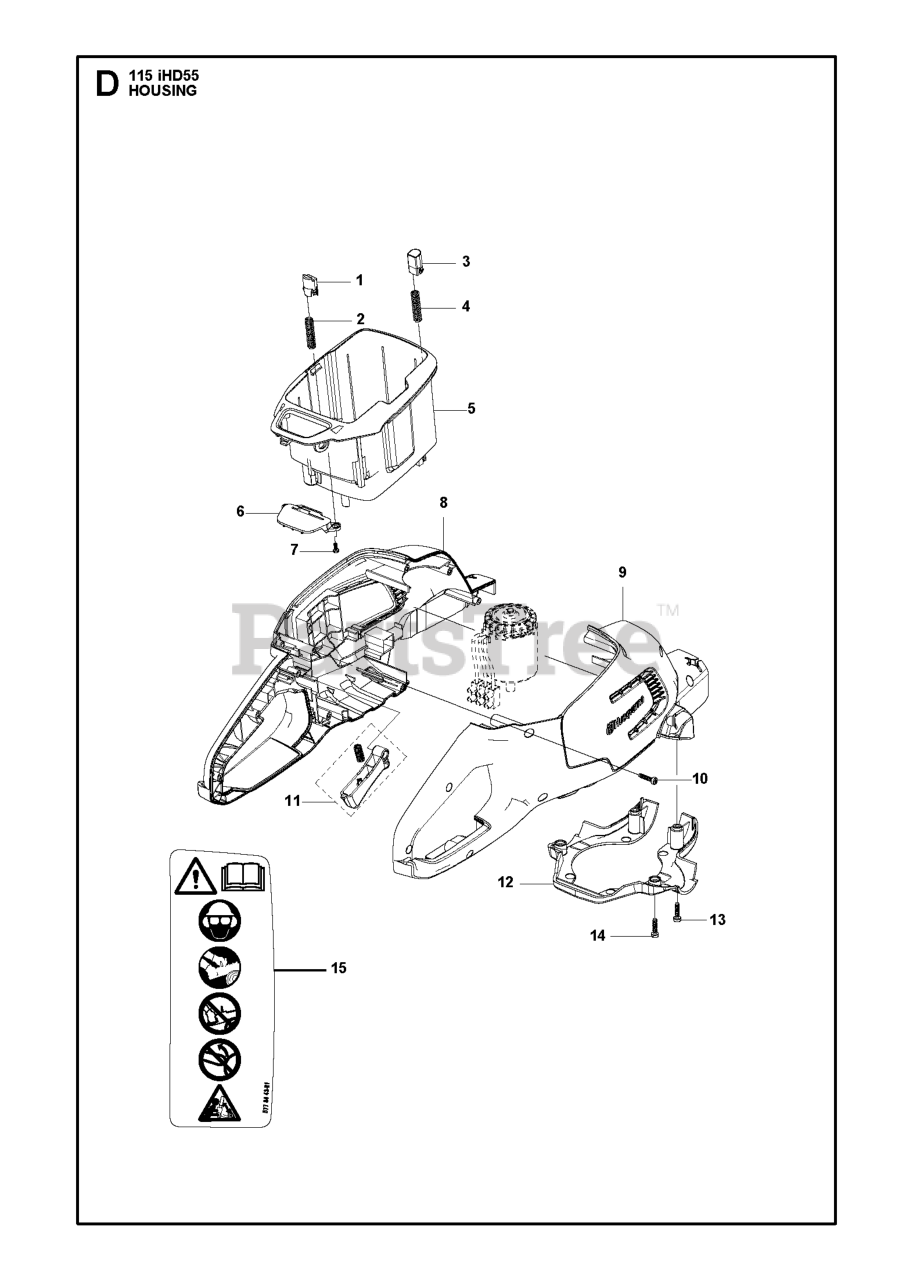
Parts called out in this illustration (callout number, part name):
1	PUSH BUTTON
2	SPRING PUSH BUTTON
3	PUSH BUTTON FRONT
4	SPRING PUSH BUTTON
5	BATTERY BOX
6	BRACKET KEYPAD
7	SCREW ST3X8
8	HOUSING LEFT - HOT FOIL+PAINTI
10	SCREW ST4X16
12	COVER BOTTOM
